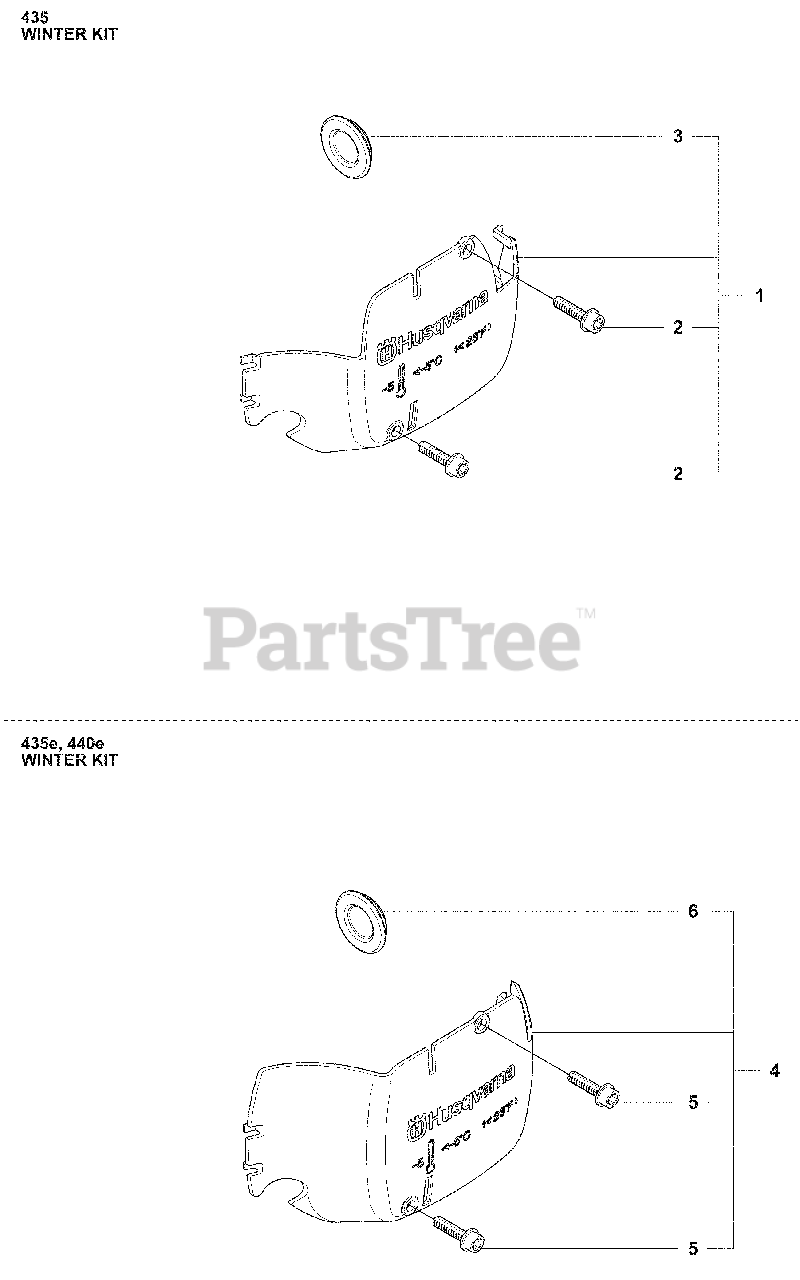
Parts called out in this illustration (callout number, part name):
1	Winter Kit
2	Screw
3	Plug
4	WINTER KIT
5	Screw
6	Plug
